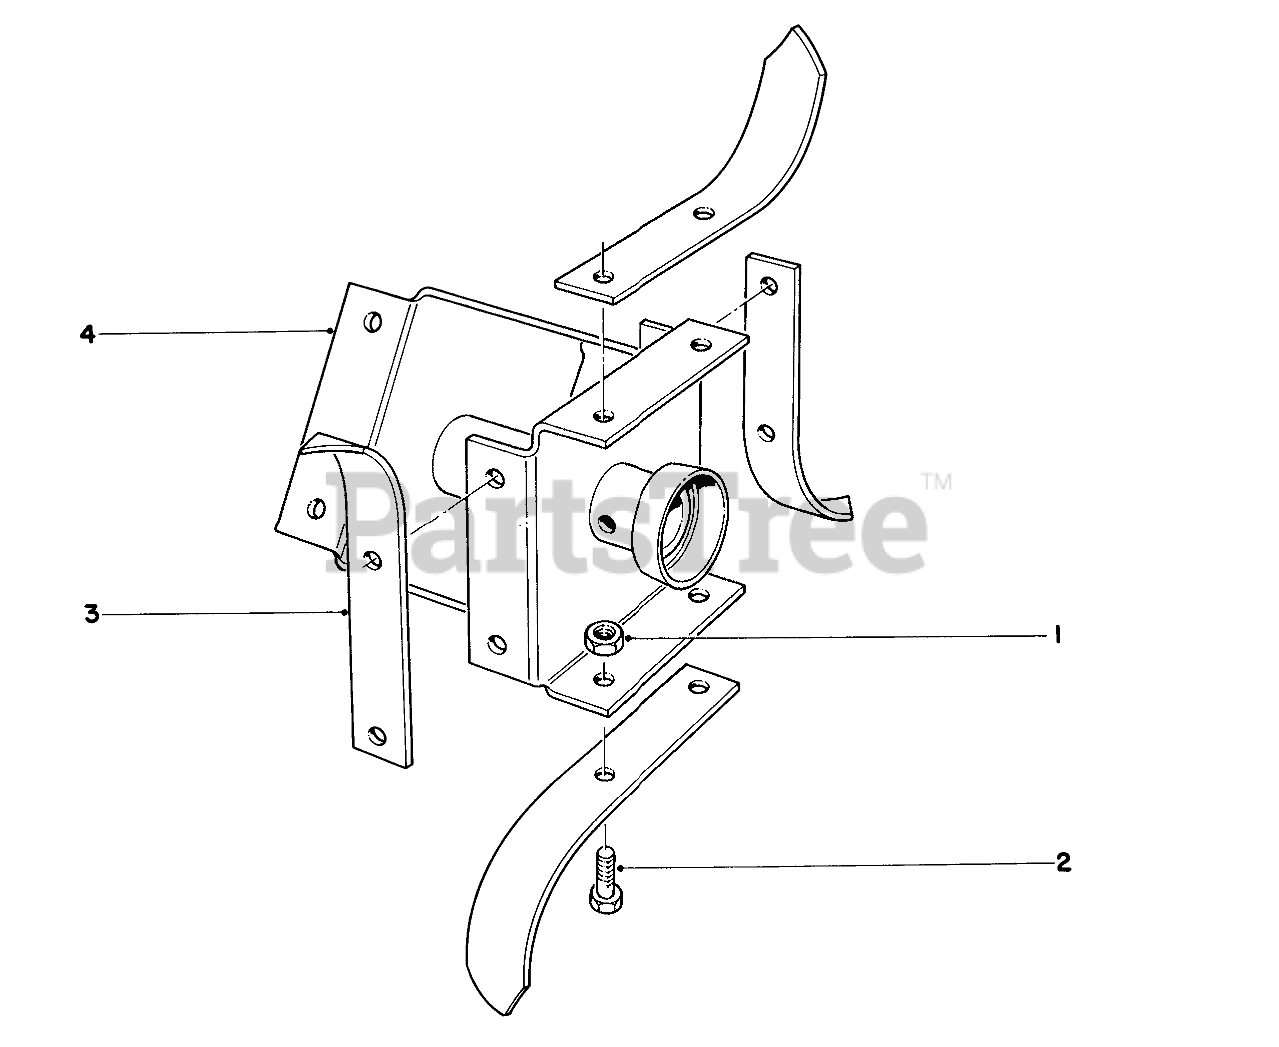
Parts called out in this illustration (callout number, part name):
1	NUT-LOCK, CONE
2	SCREW-HH
3	Pick Tine
4	Axle Welded R.H.
